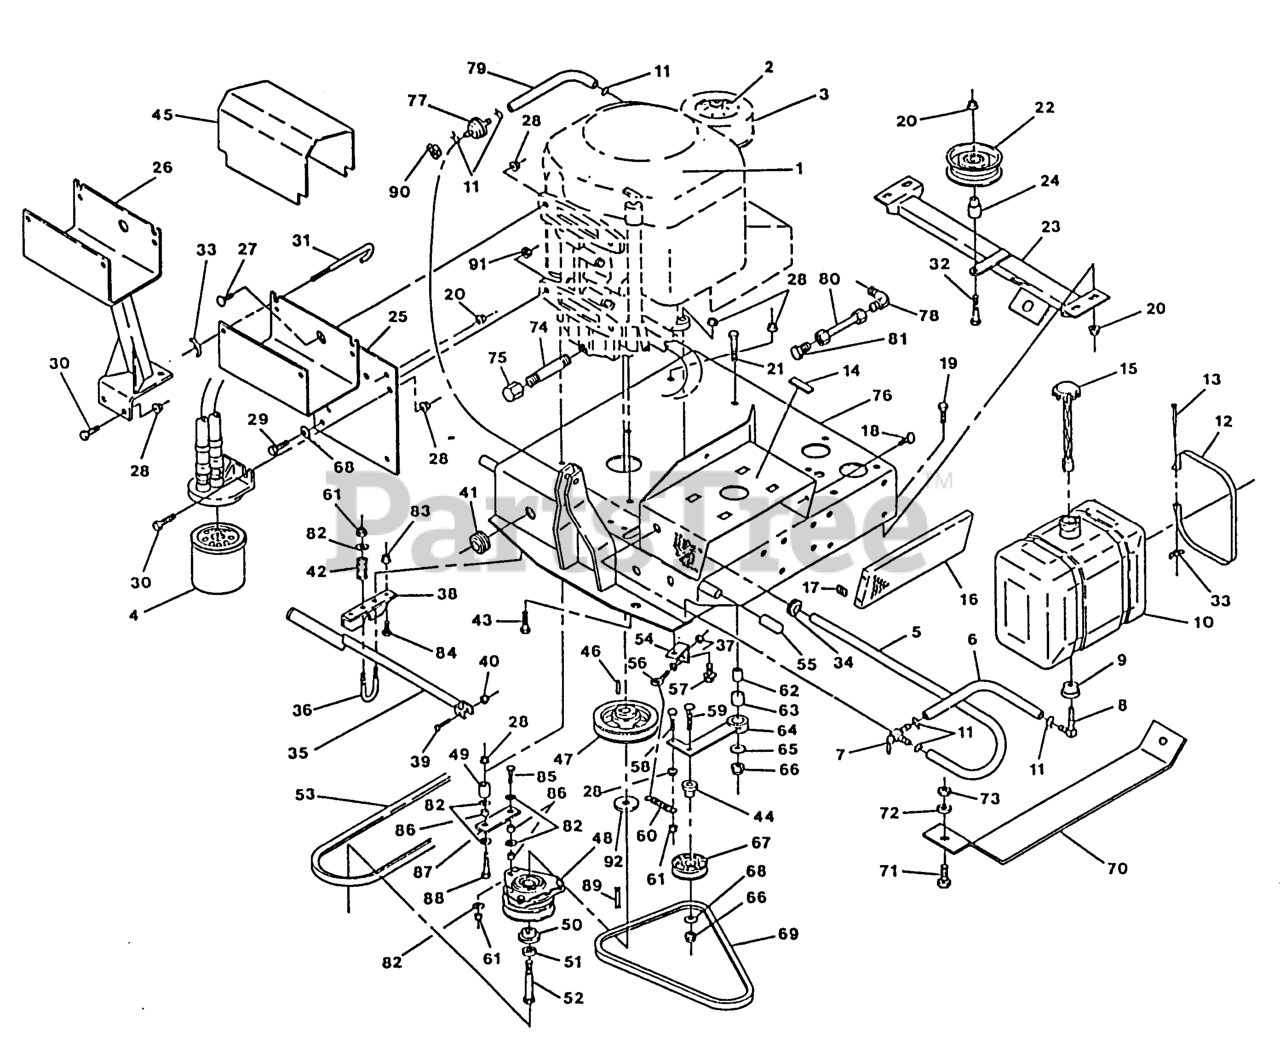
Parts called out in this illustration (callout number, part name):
1	Engine - 18 Hp Kohler
2	Air Filter
3	Foam Precleaner
4	Oil Filter
8	ELBOW-TANK, FUEL
14	PAD,PLASTIC TANK
17	NUT,RETNR UTYP 1/4-20
18	SCREW,REGTHMB,
23	WLD,CROSSMEMBER
24	BUSHING,IDLER
31	BOLT - HOLD DOWN
33	WINGNUT
34	GROMMET
36	GROMMET
40	NUT-LOCK, HH
41	GROMMET
42	SPRING-COMPRESSION
47	SHEAVE,4.25 OD A
51	WASHER-SPRING
53	BELT-DK DR FMD-60/TR
55	GRIP-LEVER, DRIVE
56	EYEBOLT-THREAD, RH
62	BUSHING,STEEL
63	BUSHING,IDLER ARM
64	WLD,IDLER ARM HYDRO
69	BELT,A TRANS DRIVE
70	PLATE-SKID
83	Nut, 1/4-20 Whizlock
90	CLAMP-HOSE
